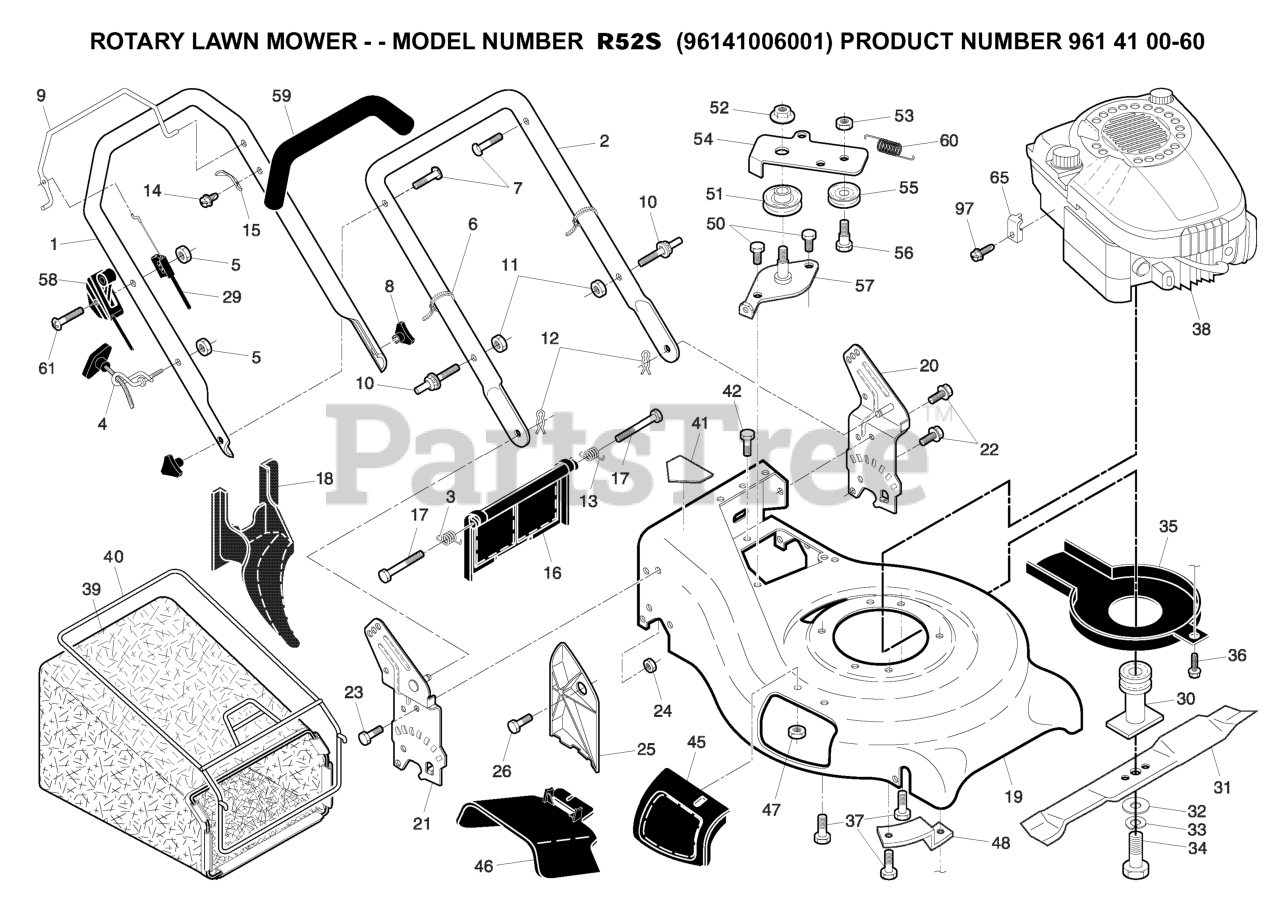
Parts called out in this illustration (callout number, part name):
2	SPRING,BRAKE RETURN
3	PULLEY TRANS
4	RETAINING RING LT
5	STRAP TORQUE
6	SCREW 5/16"
8	ROD SHIFT FENDER ADJUST LT
10	PIN COTTER
11	WASH-SHFT PLT LT
13	BOLT 1/4-28X3/4
14	LOCKWASHER
15	BOLT HEX 5/16-18 GR 5
16	NUT.71038.31-18.HEX.NYLOCK
19	NUT
21	KNOB T (1/2-HOLE)
24	NUT
25	SPRING ROD LT
26	WASHER
27	COTTER PIN
28	ROD, PARKING BRAKE
29	PLUNGER CAP
30	BRKT, MOUNT TRNSAXLE
32	BOLT
34	SHAFT, FOOT PEDAL
35	BEARING.NYLON
37	DRIVE PIN
38	PULLEY IDLER COMPOSITE
41	KEEPER, BELT IDLER
47	IDLER PULLEY
48	BELLCRANK, CLUTCH
49	RETAIN BELT
50	BOLT.3/8-16X1.50
52	LOCKNUT
53	LINK.CLUTCH.7.66.2005
55	SPRING, RETURN LT
56	SCREW.3/8-16
57	BELT, V GROUND DRIVE 95 25
59	KEEPER, BELT CENTER
61	SCREW 3/8-16X.875
62	PEDAL COVER T
63	ENGINE PULLEY
64	BOLT HEX 7/16-20X4-1/4"
65	LOCKWASHER
66	KEEPER BELT ENGINE
69	SCREW.HI-LO.CONSOLE
70	KEEPER BELT ENG
74	SPACER AXLE
77	SQUARE KEY
79	KEY STD (1373) DANA
81	SHAFT ASM CROSS TAPERED
82	SHIFT SPRING
83	WASHER
84	LINK.TRNSAXLE
85	NUT LOCK CENTER 1/4 -28 FNTHD
89	CONSOLE.SVC.SHIFT.LTST.5SP.BLK
96	RETAINER M
113	STRAP TORQUE LH LT
116	BOLT D
120	NUT LOCK FLG 3/8-16 UNC
150	SPACER, RETAINER
151	WASHER 12/32X2X10GA
156	WASHER.SRRTD.5/16
158	BRACKET
159	RB HUB.SHIFT
161	BOLT
162	NUT.CROWNLOCK.1/4
165	RP BRACKET
166	CAPSCREW.HXHD.FLG.5/16-18X.625
168	BOLT.SHOULDER.5/16-18X
169	PLATE.FASTENING.CROSS.SHAFT
170	KEEPER BELT T/A
197	NYLINER SNAP 5/8" ID
198	WASHER.NYL.7/8IDX.105"HYD CR
212	NUT
263	SCREW, 3/8-16X3/4
268	GUARD MUFFLER
275	WASHER
